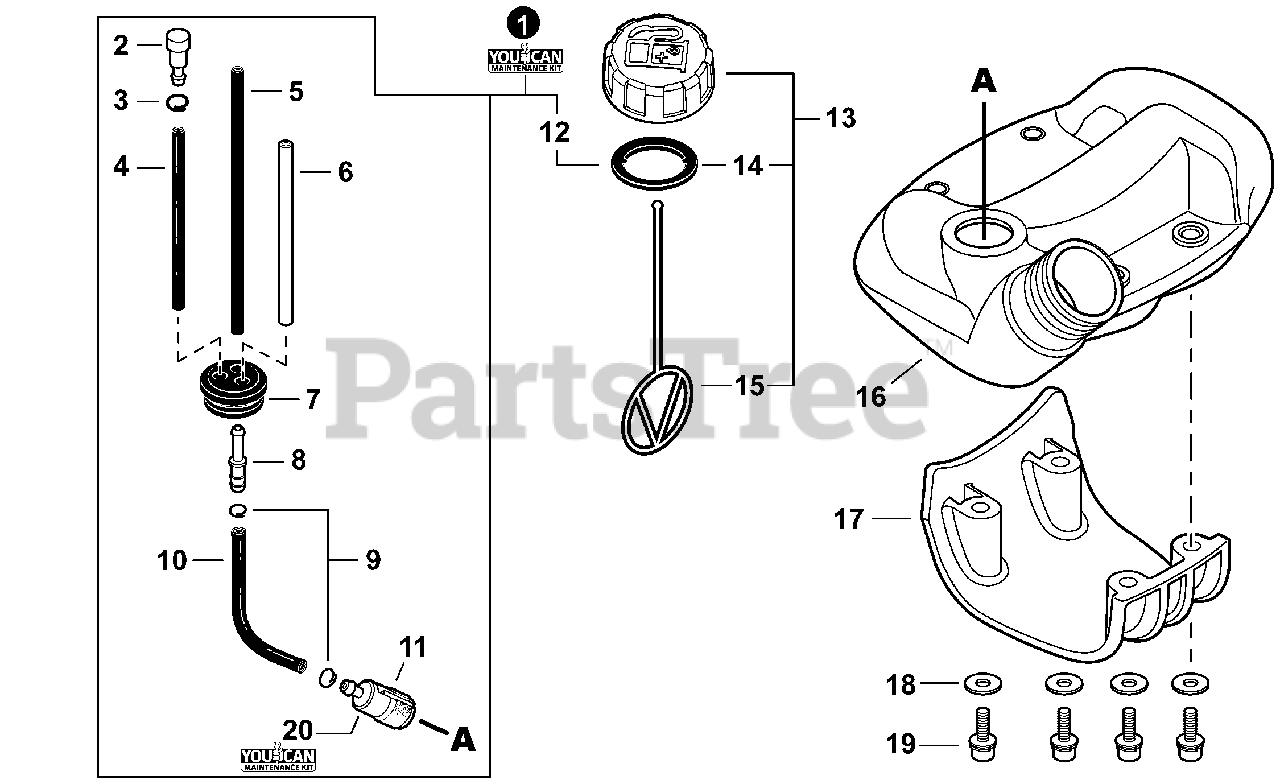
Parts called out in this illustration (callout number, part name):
1	FUEL SYSTEM KIT - YOUCANT
2	VENT ASSY
3	CLIP Ø6.5 MM
4	PIPE, FUEL 3×6×35 BLACK
5	PIPE, FUEL - 3×5×67 - BLACK
6	PIPE, FUEL 3×6×75 CLEAR
7	GROMMET, FUEL
8	CONNECTOR, PIPE Ø5ר3.5
9	CLIP Ø6
10	PIPE, FUEL - 3×5×125 - BLACK
11	FILTER, FUEL
12	GASKET, FUEL CAP
13	CAP ASSY, FUEL
14	GASKET, FUEL CAP
15	CONNECTOR, CAP L= 100 MM
16	TANK, FUEL
17	GUARD, FUEL TANK
18	WASHER 5.5×12×0.8
19	BOLT 5×25
20	TUNE-UP KIT - YOUCANT
